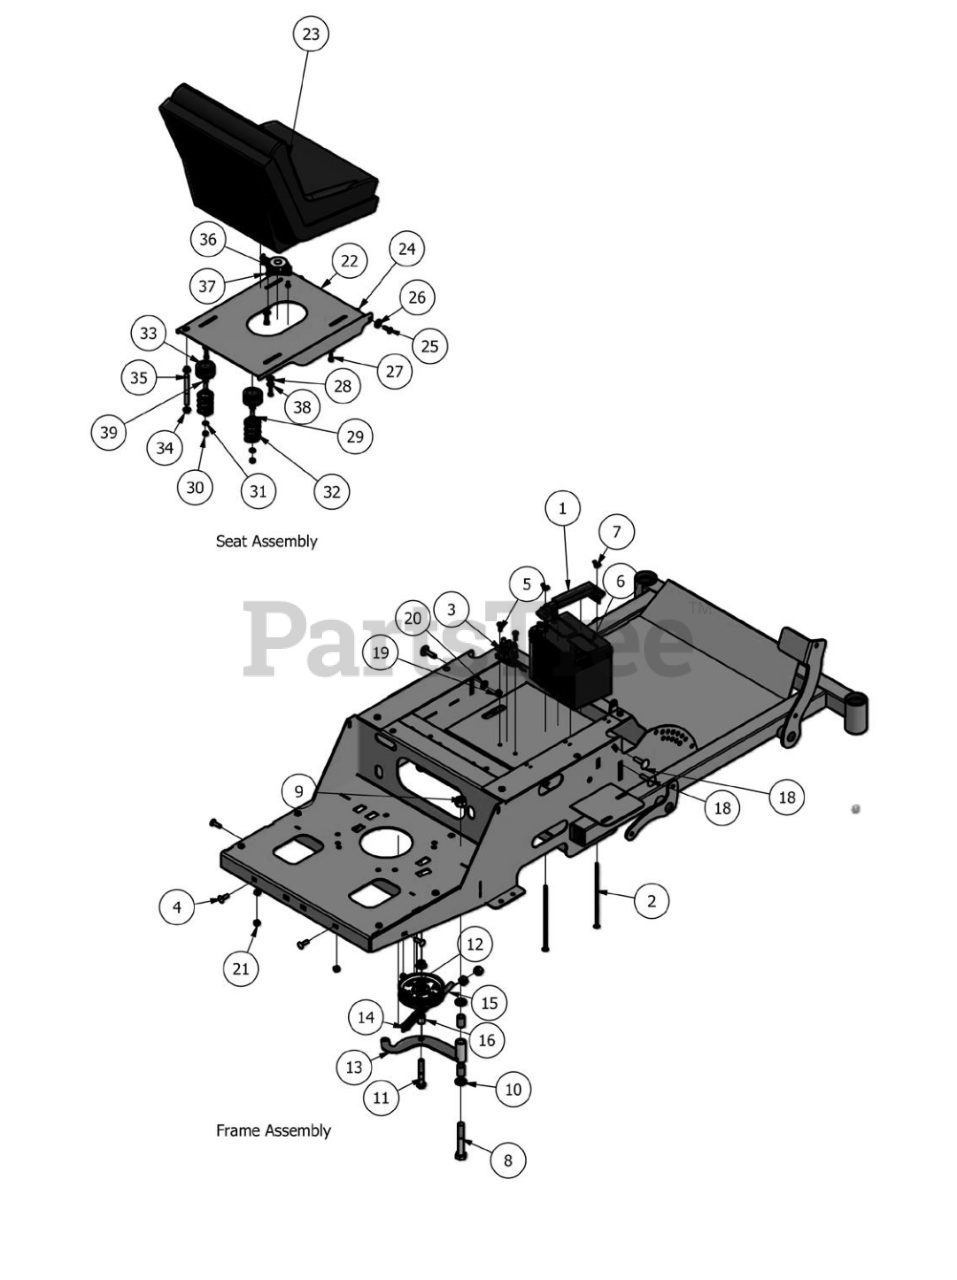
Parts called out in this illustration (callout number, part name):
1	Battery Hold Down
2	1/4-20 x 8 Carriage Bolt Zinc
3	ZT Solenoid
4	5/16-18 x 1 Carriage Bolts Zinc
5	1/4-20 x 3/4 Grade 5 Hex bolts Zinc
6	Battery (MZ)
7	1/4-20 Wing Nut Zinc
8	5/8-11 X 4 GR 5 Hex Bolts Zinc
9	5/8-11 Nylon Insert Locknut Zinc Orange Nylon
10	.630 ID X 1.122 OD X .142 THK Flat Washer Nylon
11	1/2 x 2-1/2 Hex Bolt
12	4-3/4 Idler Pulley
13	MZ Idler Arm Bracket
14	Deck Idler Spring MZ
15	Spring Tensioner
16	3/40D x 1/2ID x 3/4 Spacer
17	1/4" Drive in Grease Fitting
18	3/8 x 1-1/2 Carriage Bolt
19	3/8-16 Hex Nuts Zinc
20	3/8 USS Flat Washer Zinc
21	5/16-18 Nylon Insert Locknut Zinc Orange Nylon
22	MZ Seat Plate
23	Gray Bucket Seat with no Arms/Sides
24	5/16-18 Nylon Insert Flange Nut Zinc Orange Nylon
25	5/16-18 x 1 Carriage Bolts Zinc
26	.360ID Plastic Washer
27	5/16-18 x 1 Grade 5 Hex bolt Zinc
28	5/16 USS Flat Washer Zinc
29	3/8 USS Flat Washer Zinc
30	3/8-16 Hex Nuts Zinc
31	3/8 Lockwasher Zinc
32	Seat Spring
33	Seat Bumper
34	1/2-13 Hex flange Nut Zinc w/Serrations
36	Seat Saftey Switch
37	1/4-20 x 1/4 Hex Washer Head Bolt Slot Type
38	5/16 Lock Washer Zinc
39	3/8-16 x 1-1/4 GR 5 Hex Bolt Zinc
